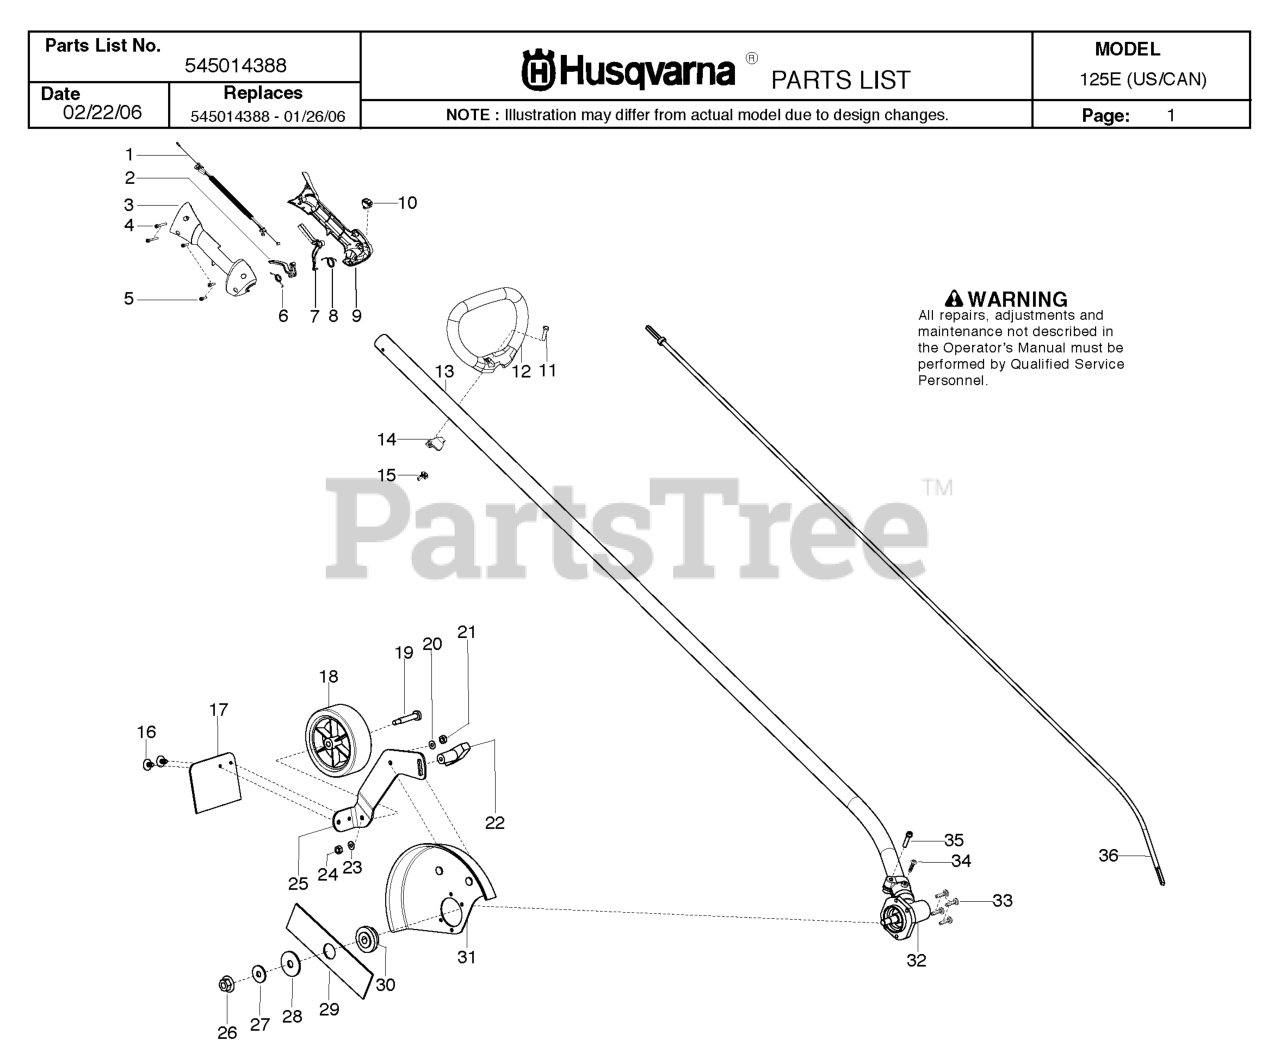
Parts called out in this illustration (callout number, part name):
1	%ASSY CABLE WIRE HARNESS
2	TRIGGER THROTTLE
3	HOUSING-THROTTLE RH
5	SCREW M4 X 1.75 PT 16MM
6	SPRING TRIGGER
7	THROTTLE LOCKOUT
8	SPRING LOCKOUT
9	HSG THROTTLE LH
10	KIT SWITCH
11	BOLT, TYPE 2
13	KIT-DRIVESHAFT
14	CLAMP ASSIST HANDLE
15	WINGNUT, TYPE 2
16	FASTENER MUD FLAP
17	KIT MUD FLAP
18	WHEEL-4"(FRONT)(RUBBER)
19	BOLT-SHOULDER AXLE
25	WHEEL BRKT ADJ
26	NUT-FLANGE (LH)
27	WASHER BELLVILLE
28	WASHER-FLAT.
31	KIT - EDGER GUARD
32	KIT GEARBOX EDGER HUSQ
33	SCR 10-24 MS LDK PAN PH
34	SCREW 8-16 X 9/16 (PLAS
35	SCREW - CARB. ADAPTOR
36	FLEXSHAFT 57"
